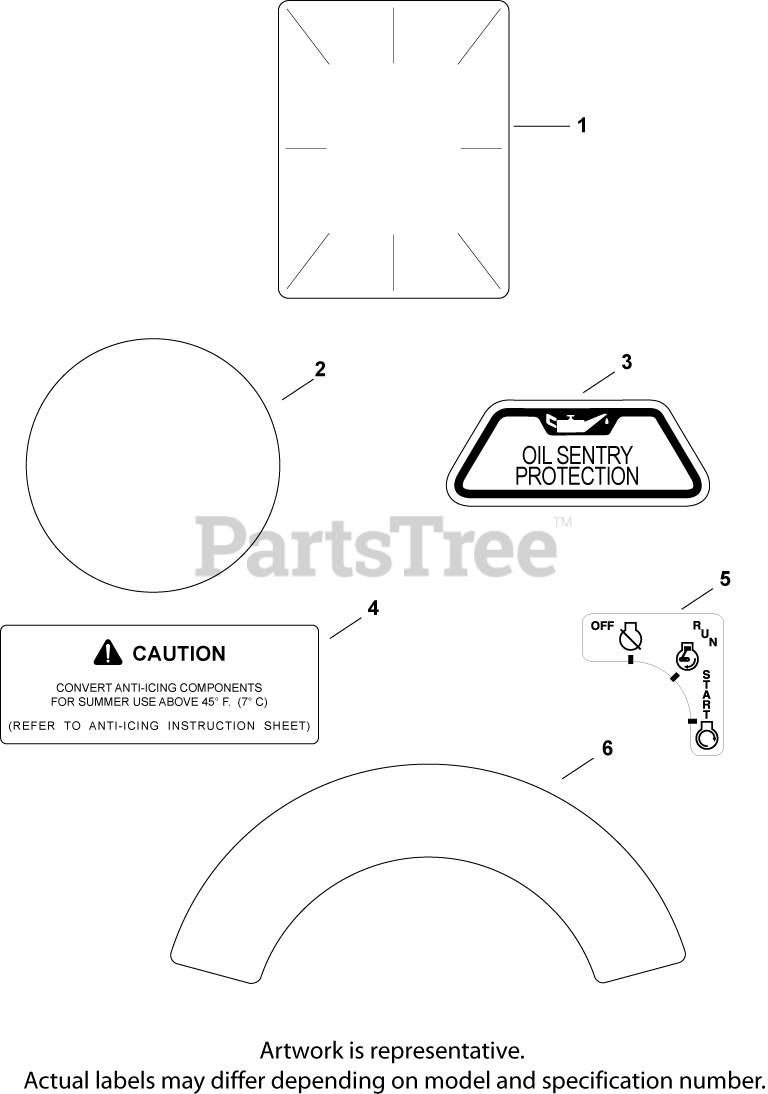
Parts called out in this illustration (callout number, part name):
1	DECAL, CLEAR LAMINATE USE 25 113 70-S
2	DECAL, GRASS SCREEN USE 24 113 499-S
3	DECAL, OIL SENTRY - (#DSC)
4	DECAL, ANTI-ICING
5	DECAL, KEY SWITCH
6	DECAL, COMMAND 27 HP
